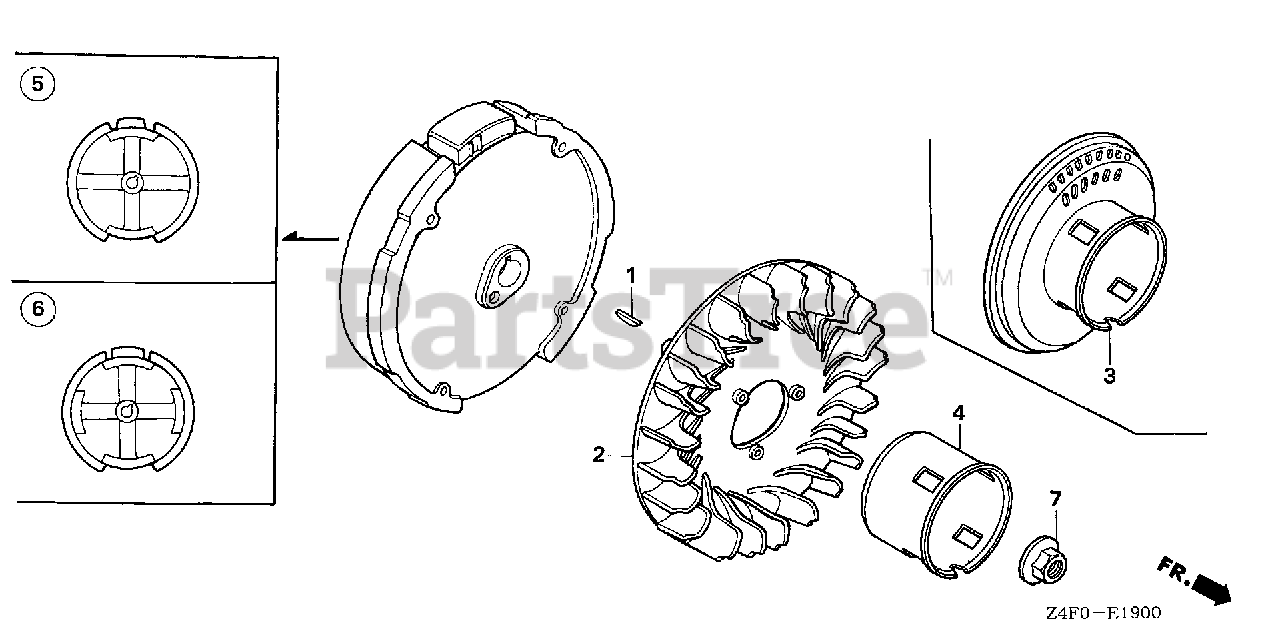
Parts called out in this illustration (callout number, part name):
1	KEY, SPECIAL WOODRUFF (25X18)
2	FAN, COOLING
3	PULLEY, STARTER
5	FLYWHEEL
7	NUT, SPECIAL (14MM)
